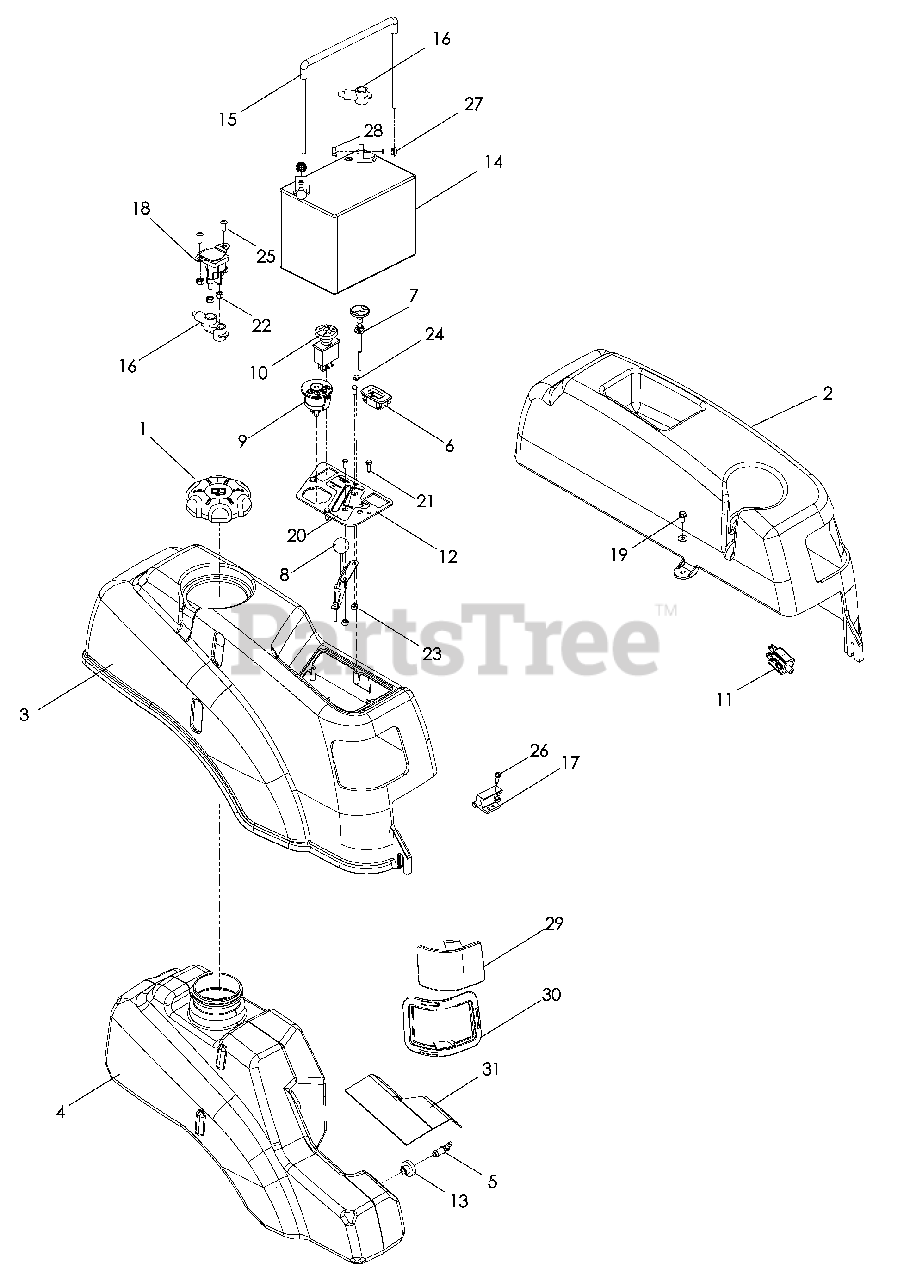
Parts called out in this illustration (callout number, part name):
2	FENDER, LT
3	FENDER, RT
4	TANK, FUEL
5	ELBOW, TANK
6	HOUR METER
7	CONTROL, CHOKE 96588401 ONLY
8	CABLE, THROTTLE 96588401 ONLY
9	SWITCH, IGNITION
10	SWITCH, CLUTCH
11	SWITCH, BRAKE
12	PLATE, CONTROL
13	GROMMET, RUBBER
14	BATTERY
15	TIE DOWN, BATTERY
16	TERMINAL COVER
17	SWITCH, NC
19	BOLT ¼-20 x ½ HWST
20	DECAL, CONSOLE
21	SCREW 10-24 x ½ SLT HD
22	NUT ¼-20 HEX NYLOC
23	NUT 10-24 HEX NYLOC
24	SCREW 10-12 x ¾ WSH HD
25	SCREW ¼-20 x 5/8 BTN SKT
26	SCREW 10-24 x 5/8 WSH HD
27	RHSNB 5/16-18 x ¾
28	NUT 5/16-18 HEX WHIZLK
29	LENS, LT
30	LENS, RT
31	LENS RIM, LT
